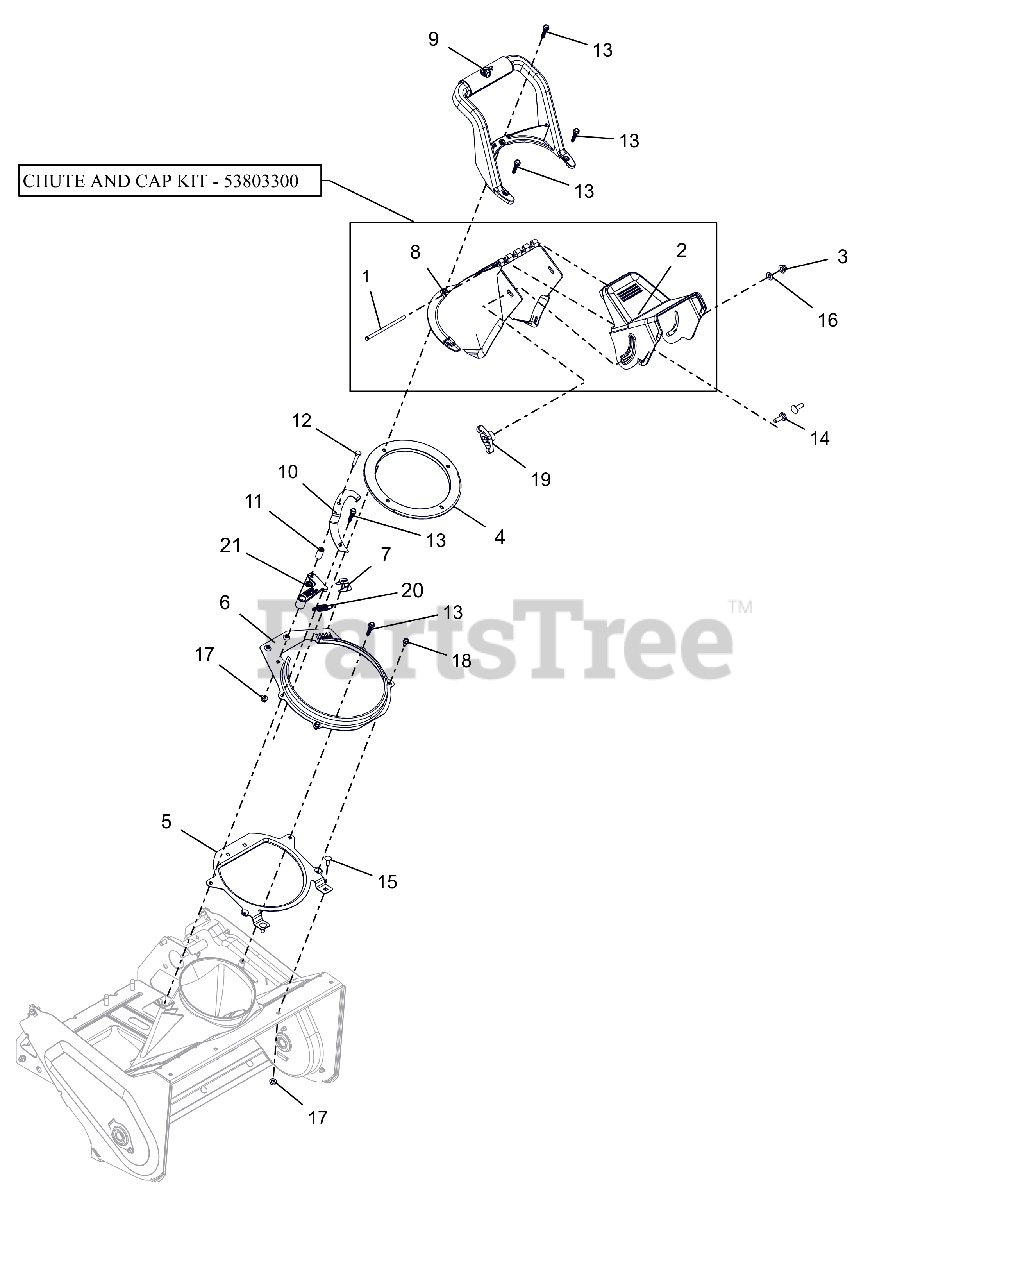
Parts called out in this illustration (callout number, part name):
1	ROD, CONNECTING, 1/4 X 4-1/2
2	KIT, CAP REPLACEMENT
3	@NUT-LK-NYL-FLG .31-18 YWZC
4	GUARD, WATER
5	RING, CHUTE MOUNT - LOWER
6	RING, CHUTE MOUNT - UPPER
7	BRKT, SPRG
8	KIT, CHUTE AND CAP REPLACEMENT
9	CHUTE, HANDLE SINGLE STAGE
10	PAWL ARM STOP
11	BSHG, SLV .265X.505X.995
12	@BLT-HEX .25-20X1.50 GR5 YWZC
13	SCR-TAP .25-10X1.25 HWH YWZC
14	BLT,RNHDRECSHNK .31-18X1.00
15	@BLT-RDHDSQNK .25-20X.75 G5YZ
16	@WSHR-FL-STL.344X.688X.065YWZC
17	@NUT-LK-TOP-FLG .25-20 YWZC
18	SCR-TAP .25-20X.50 HWH TR YWZ
19	KNOB,WING .31-18 UNC NYL/TALC
20	SPRG, TENSION .052X.520X1.74
21	KIT, PAWL ARM REPLACEMENT
22	KIT, CHUTE AND CAP REPLACEMENT
